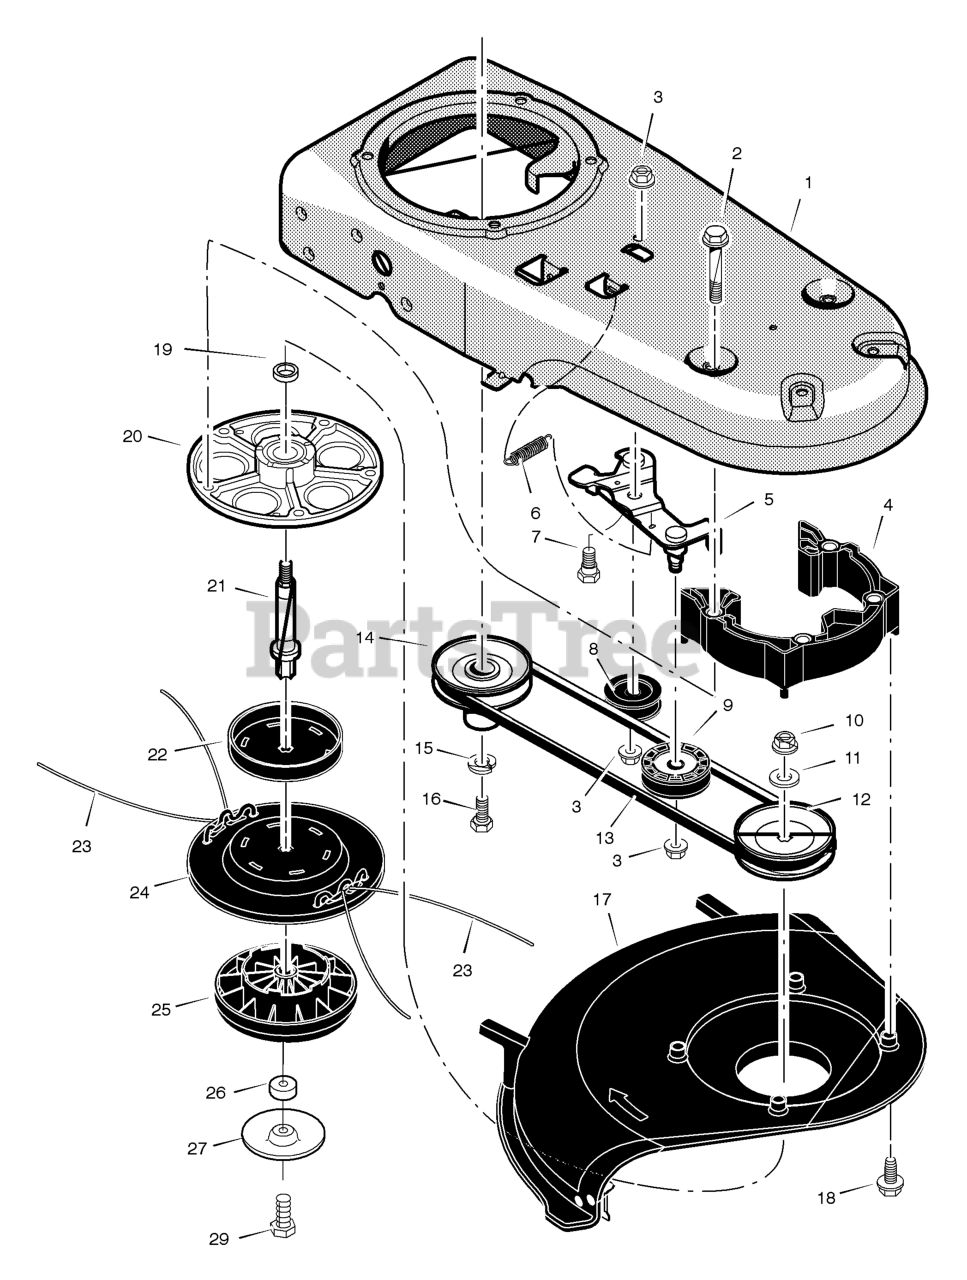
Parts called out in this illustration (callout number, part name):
1	Frame, Trimmer
2	Bolt
3	Nut
4	Spacer Assembly, Jackshaft
5	Bracket, Idler Asembly
7	Bolt, Shoulder
8	Pulley, Idler
9	PULLEY, IDLER, V, 1.88
11	Washer
12	Pulley, Cutting Head
14	Pulley, Drive
15	Washer
17	Shield, Trimmer
19	Spacer
20	Housing, Jackshaft
21	Jackshaft
22	Shield, Weed
23	Line, 0.130" x 16.75 (24 pack)
24	Head, Cutting
25	Guide, Height
27	Washer
